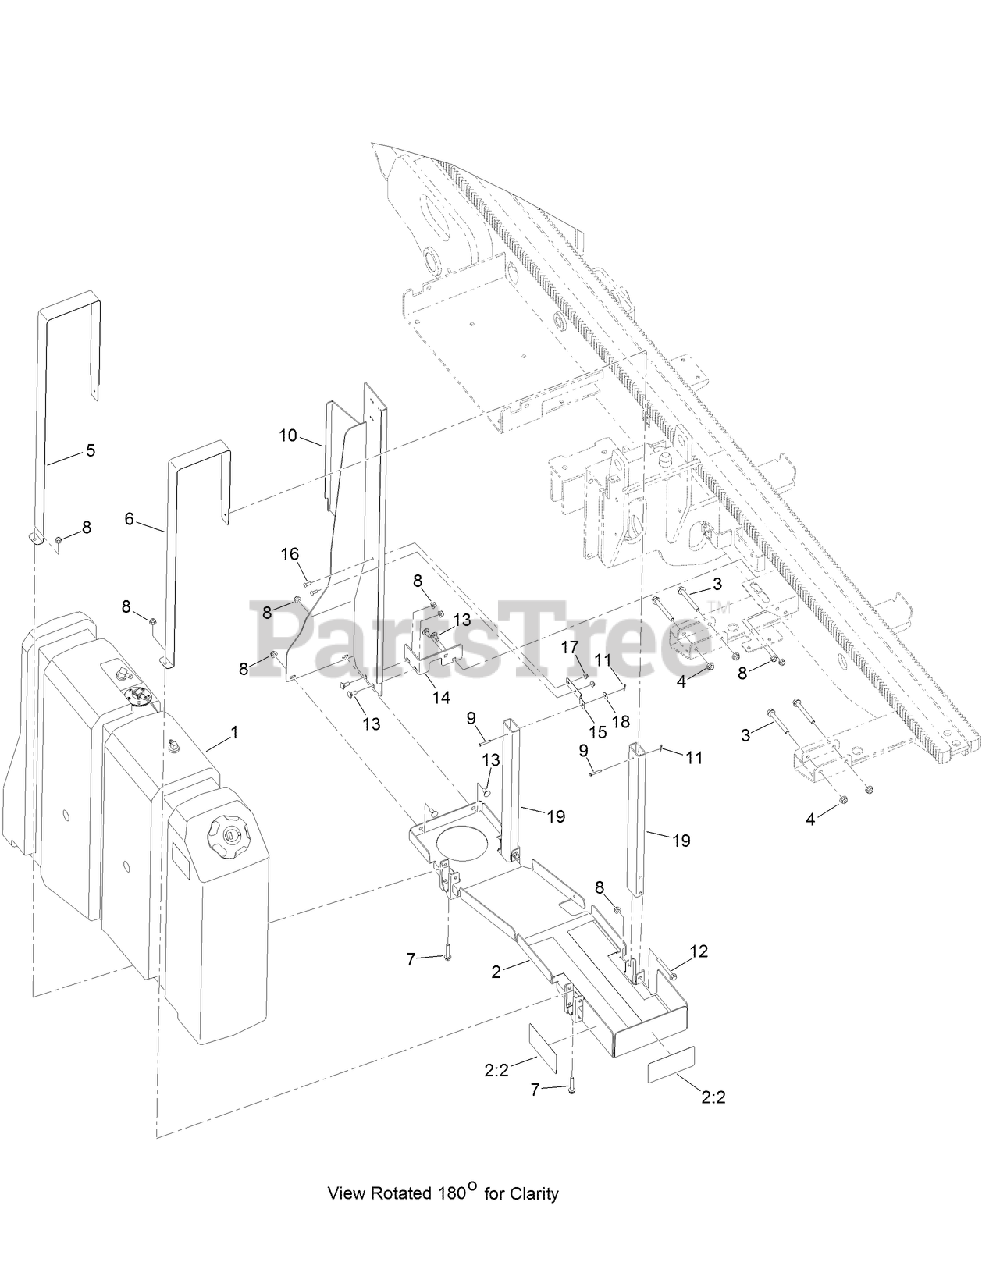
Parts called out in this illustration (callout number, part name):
1	FUEL TANK ASM
2	SUPPORT-TANK, FUEL
2:2	DECAL-DANGER, CRUSHING
3	SCREW-HHF
4	NUT-HF, NI
5	STRAP-FUEL TANK, FRONT
6	STRAP-FUEL TANK, REAR
7	SCREW-HWH
8	NUT-HF, NI
9	CLEVIS PIN
11	PIN-COTTER
12	SCREW-HHF
13	SCREW-CARR
14	MOUNT-SHIELD
15	PLATE-GUARD
16	SCREW-HSBH
17	NUT-HF
18	WASHER-FLAT
19	TUBE-TANK, FUEL
